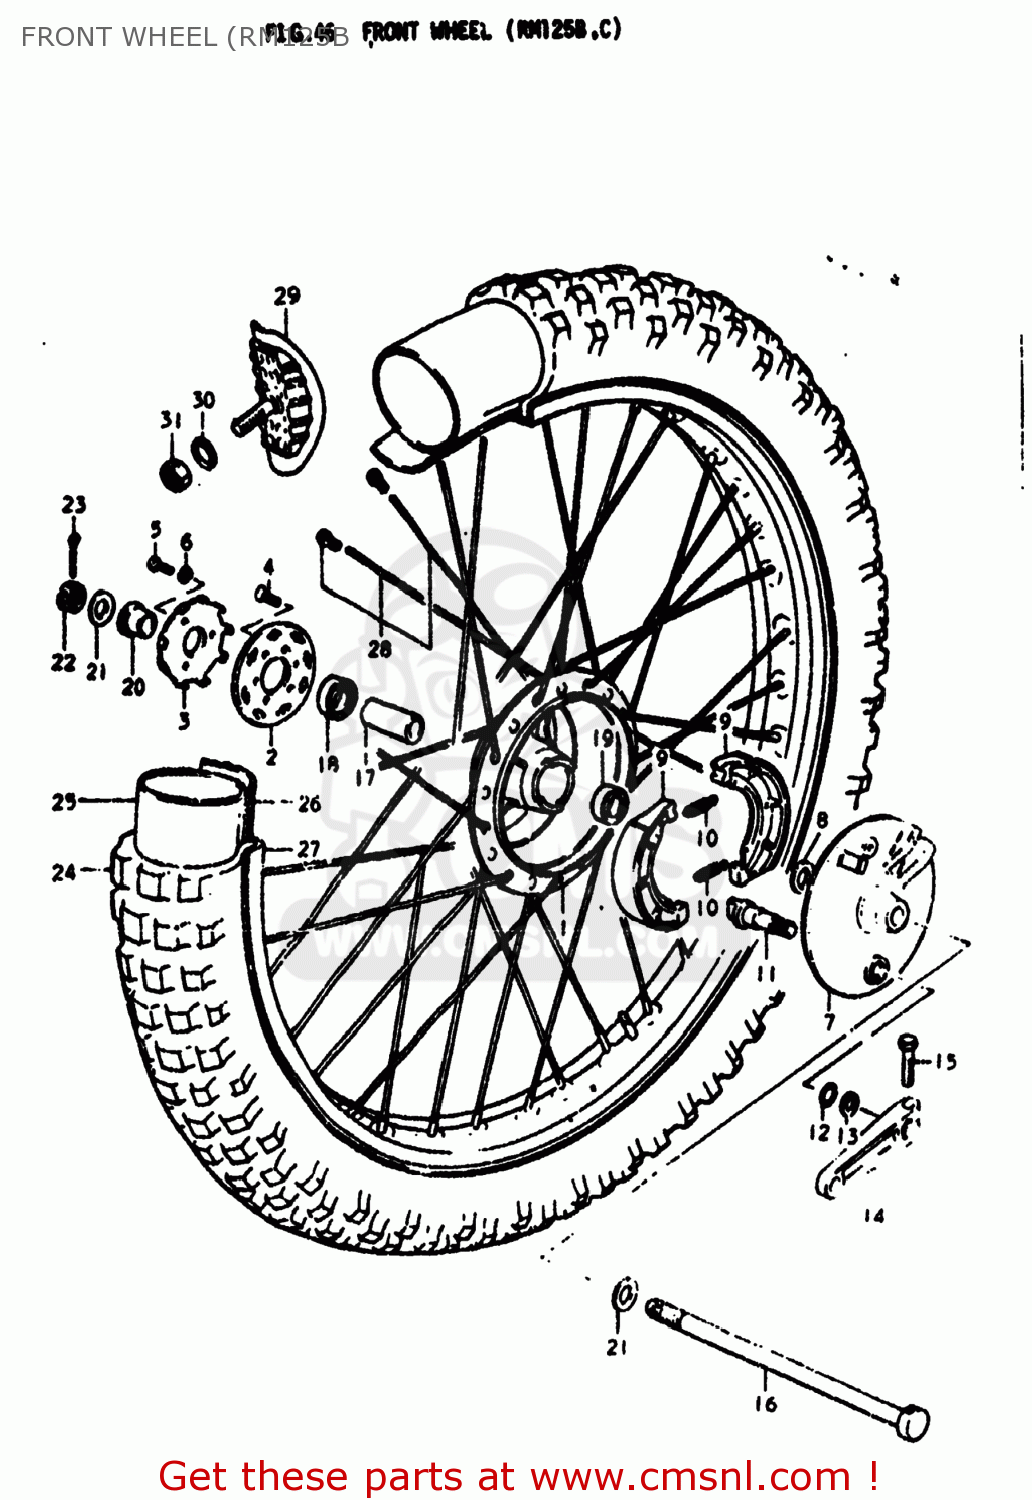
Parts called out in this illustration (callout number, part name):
1	HUB,FRONT
2	FLANGE,FRONT HUB,RIGHT
3	RETAINER,FR HUB BEARING,R
4	SCREW
5	BOLT, UPPER
6	LOCK WASHER
7	PANEL,FRONT HUB
8	BOSS
9	SHOE,BRAKE
10	SPRING(L:34)
11	CAM,FRONT BRAKE
12	O RING(D:2.5,ID:11.4)
13	WASHER(12.5X20X1)
14	LEVER,FRONT BRAKE CAM
15	BOLT
16	AXLE,REAR
17	SPACER (12.6X19X52)
18	BEARING
19	BEARING, LH
20	SPACER,FR AXLE,R
21	WASHER
22	NUT, REAR AXLE
23	COTTER PIN
24	TIRE,FRONT
25	TUBE
26	PROTECTOR,WHEEL,INNER
27	RIM,FRONT WHEEL
28	SPOKE SET,FRONT
29	STOPPER,BEAD
30	WASHER
31	NUT
